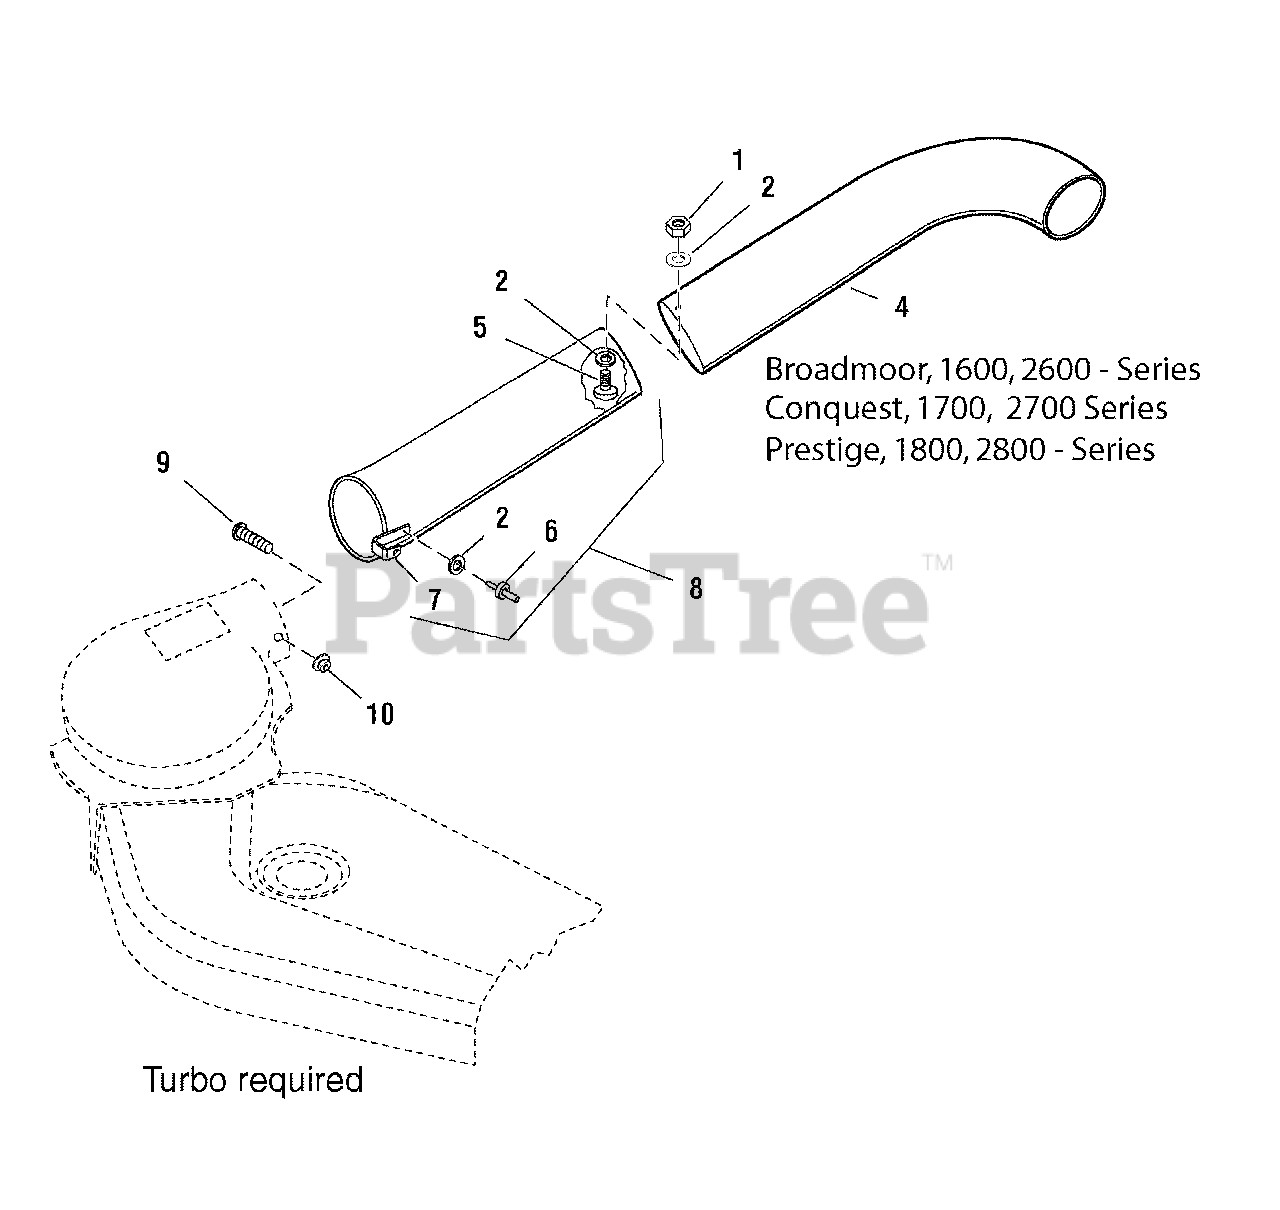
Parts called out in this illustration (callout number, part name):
1	NUT, Hex Nylock, #10-32
4	ELBOW, Upper
5	SCREW, Truss Head, #10-32 x 1/2
7	CLIP, Spring
8	TUBE & SPRING ASSEMBLY (Incl. Ref. Nos. 2, 6, & 7)
9	CARRIAGE BOLT, 1/4-20 x 5/8
10	NUT, Hex Flange Lock, 1/4-20
